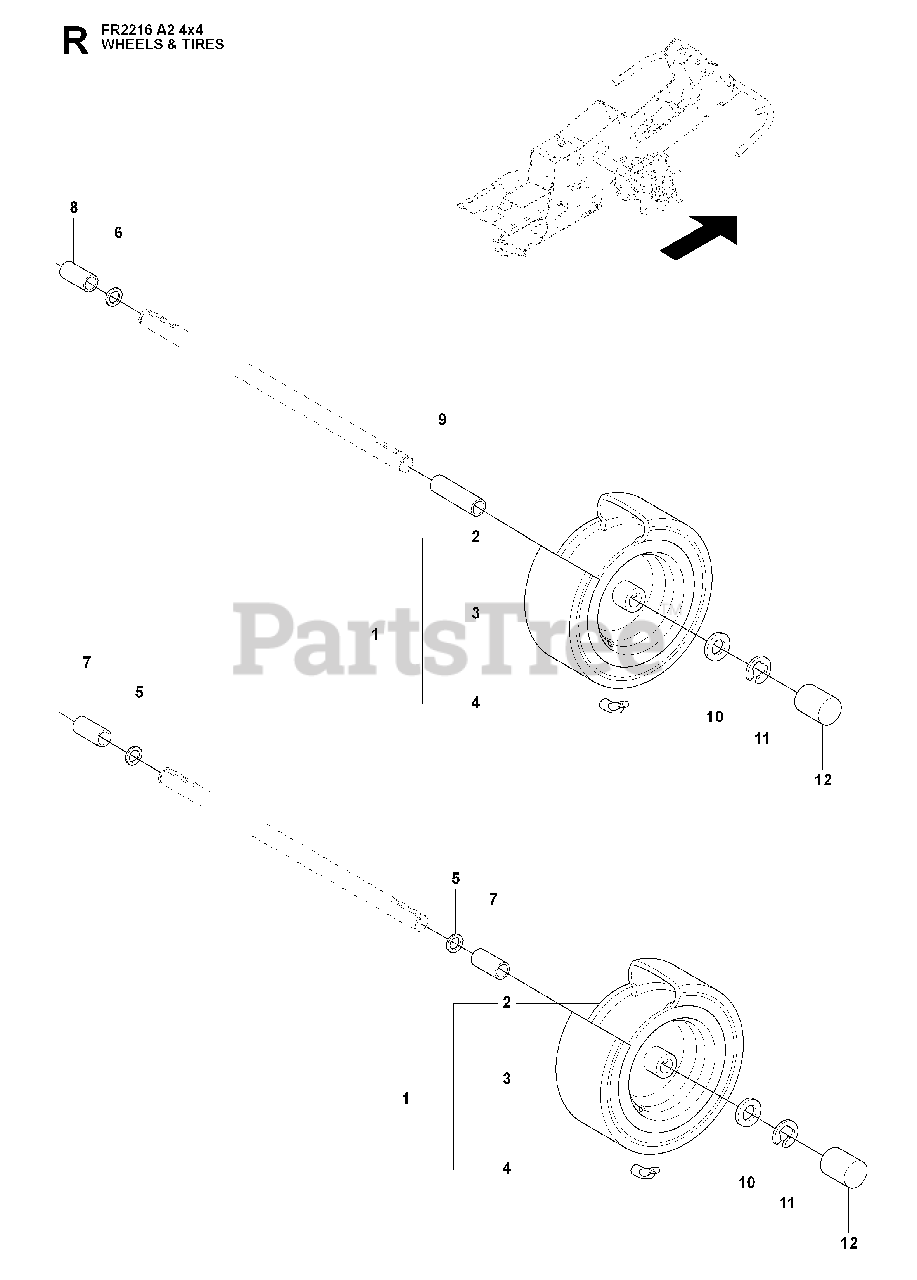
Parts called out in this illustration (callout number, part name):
2	RP RIM
7	SPACE SLEEVE
11	RETAINING RING
12	DUST CAP
